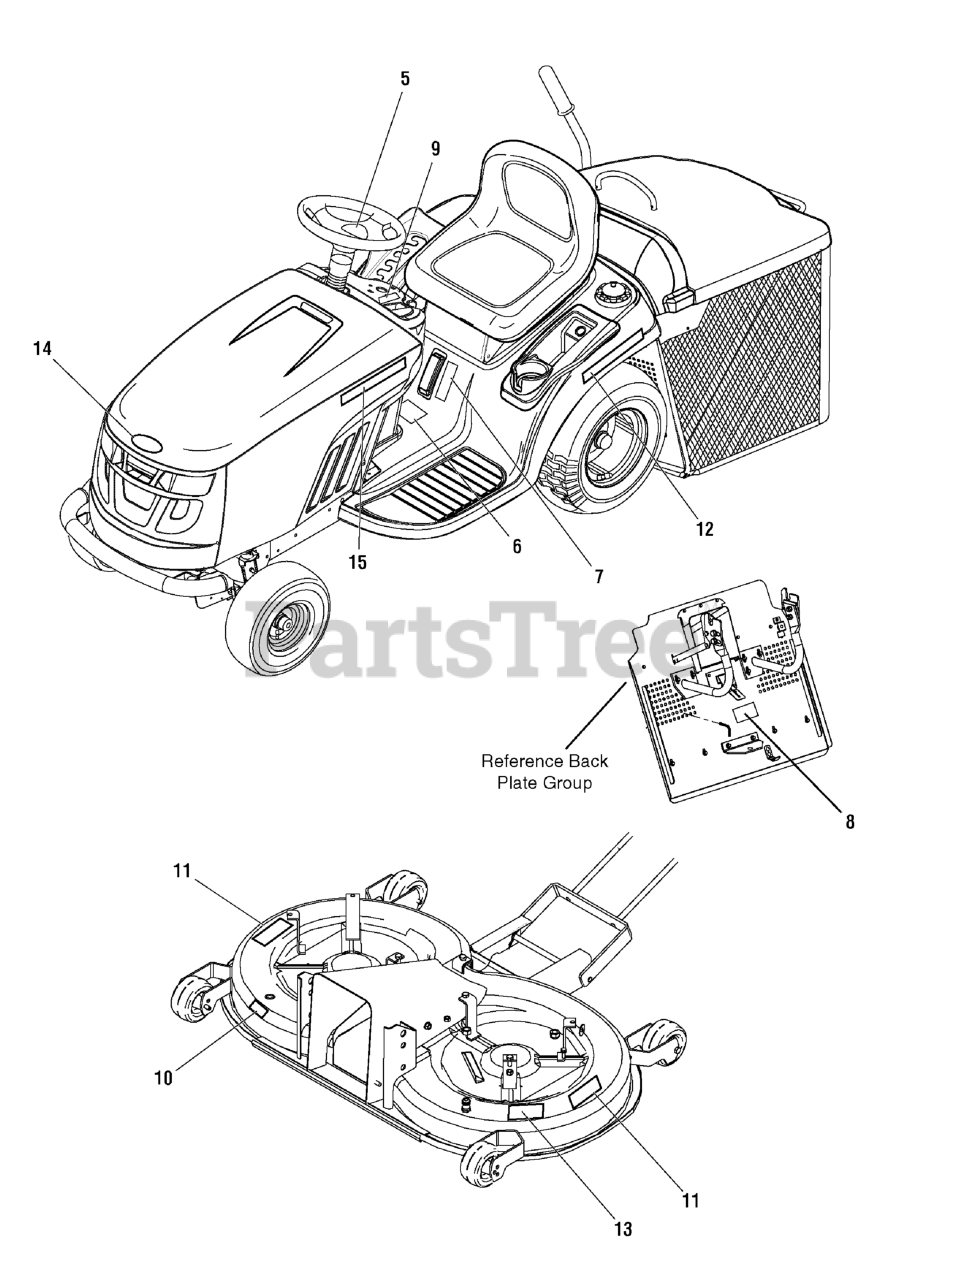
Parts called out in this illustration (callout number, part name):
5	DECAL, Steering Wheel
6	DECAL, Tunnel Cover Warnings, Export
7	DECAL, Fuel Level
8	DECAL, Hydro Release
9	DECAL, Ignition Switch Symbols
10	DECAL, Noise
11	DECAL, Safety
12	DECAL, Model
13	DECAL, 102cm
14	DECAL, Logo
15	DECAL, Performer
